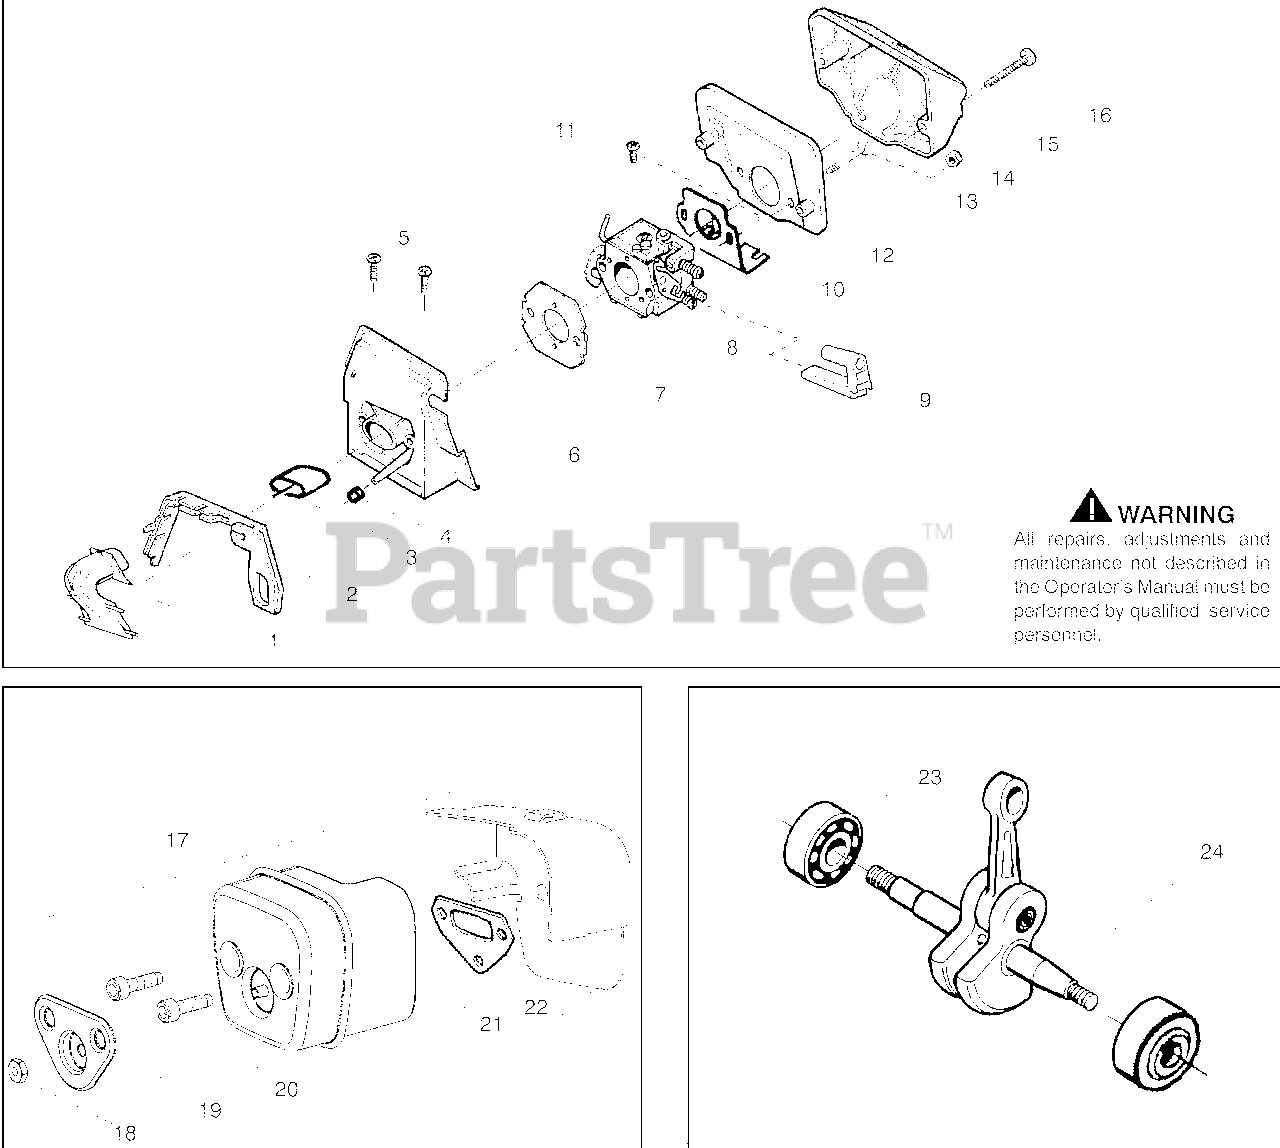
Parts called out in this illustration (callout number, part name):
1	Assy--Turbo Air Cleaner
2	Seal -- Turbo Clean
3	Sleeve--Intake
4	Seal--Impulse
6	Adapter -- Carb.
7	Gasket--Carburetor
8	Carburetor
9	Grommet--Final
10	Plate -- Support
12	Air Filter -- Bottom
13	Stud -- Carb.
15	Air--Filter -- Top
17	Kit--Muffler
18	Nut--Brass
19	Cover--Bolt
20	Bolt--Muffler
21	Gasket--Muffler
22	Backplate--Muffler
23	Assy. --Bearing and Seal
24	Assy--Crankshaft & Rod
